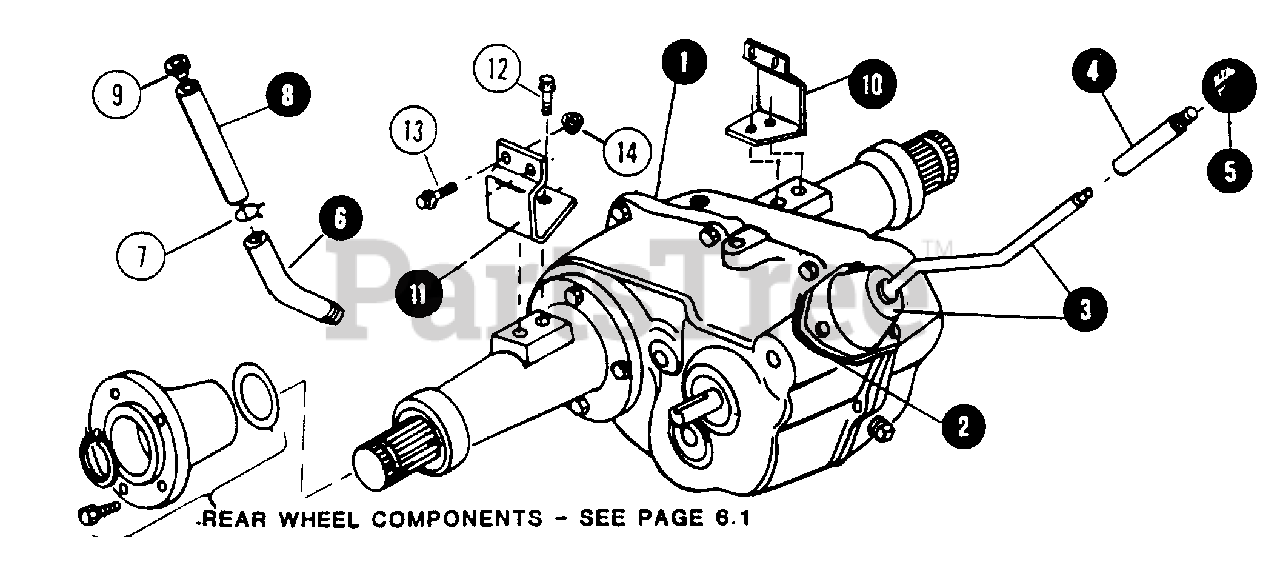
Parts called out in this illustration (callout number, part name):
1	TRANSAXLE ASSEMBLY - COMPLETE
2	GASKET, SHIFT LEVER HOUSING
3	LEVER, SHIFT
4	EXTENSION, SHIFTER
5	KNOB, SHIFT LEVER
6	NIPPLE, OIL FILLER
7	CLAMP, HOSE TO NIPPLE
8	HOSE, TRANSAXLE OIL FILLER
9	PLUG, OIL FILLER HOSE
10	BRACKET, L. H. MOUNTING
11	BRACKET, R. H. MOUNTING
12	BOLT 3/8C x 1 FLANGE
13	BOLT, 1/2C x 1-1/4 HEX FLANGE
14	NUT, 1/2C FLANGE LOCK
